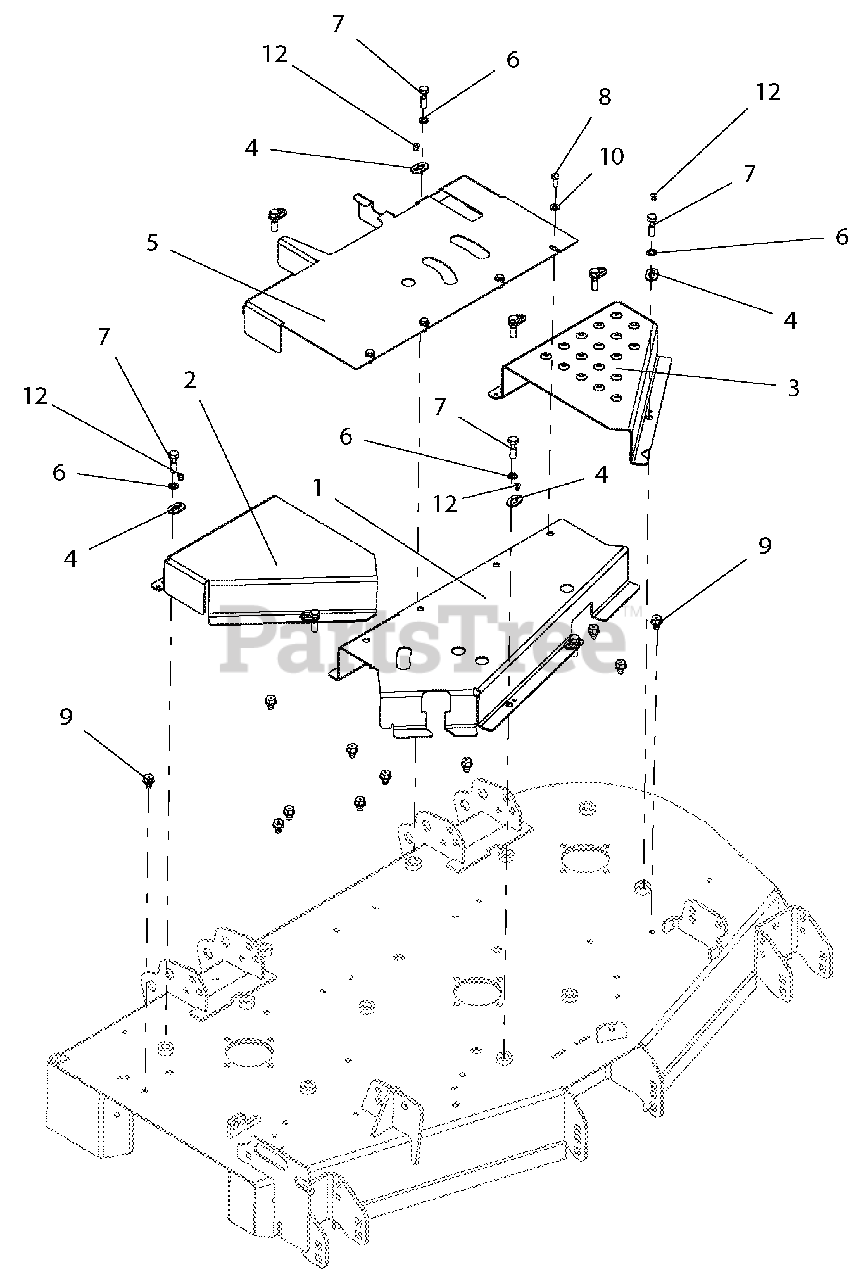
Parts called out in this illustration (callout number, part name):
1	WLDMT, FRONT BELT SHIELD (BLACK)
2	GUARD, RH PT200 CE BELT (BLACK)
3	GUARD, LH PT200 CE BELT (BLACK)
4	KEEPER, BOLT
5	SHIELD, BELT REAR (BLACK)
6	LOCK, WSHR-EXT 0.391 X 0.628 X 0.036 YWZC
7	BLT, HEX 0.38-16 X 1.25 GR5 CAPTIVE
8	BLT-HEX .25-20X.75 GR5 YWZC
9	SCR-TAP .38-16X.50 HWH TR YWZ
10	WSHR-FL-STL.281X.62X.065 YWZC
12	RVT-POP .187x.250 (#64) YWZC
